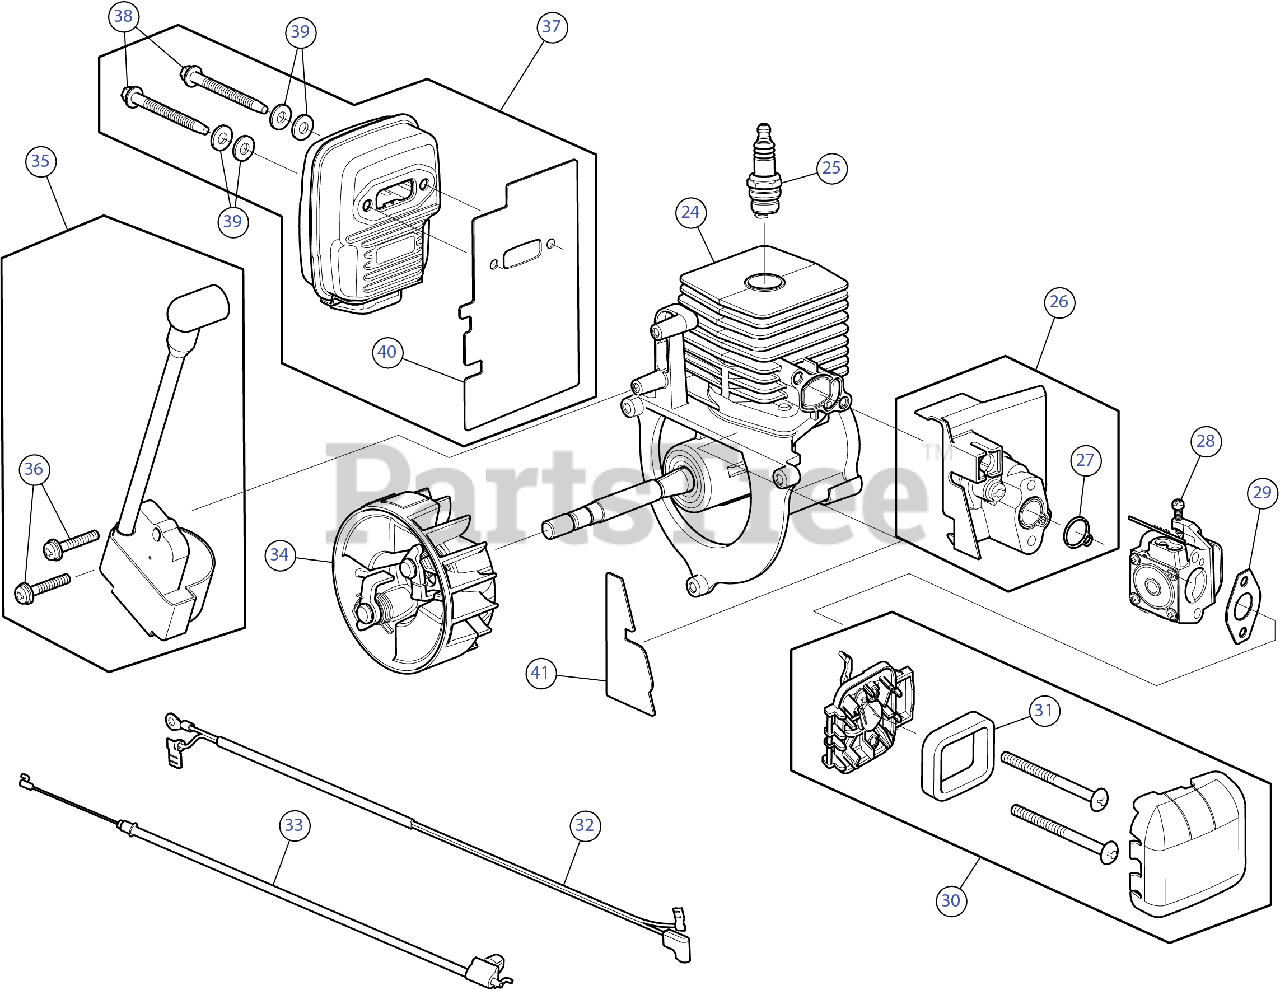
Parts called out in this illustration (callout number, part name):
24	SHORT BLOCK
25	SPARK PLUG
26	INTAKE ASSEMBLY
28	CARB ASSEMBLY
29	GASKET CARB
30	AIR CLEANER ASSEMBLY
33	THROTTLE CABLE
34	FLYWHEEL ASSEMBLY
35	MODULE
36	SCREW 8-32X.750
37	MUFFLER ASSEMBLY
38	MUFFLER SCREW
39	WASH, FLAT .480X.1
41	SHORTBLOCK GASKET
